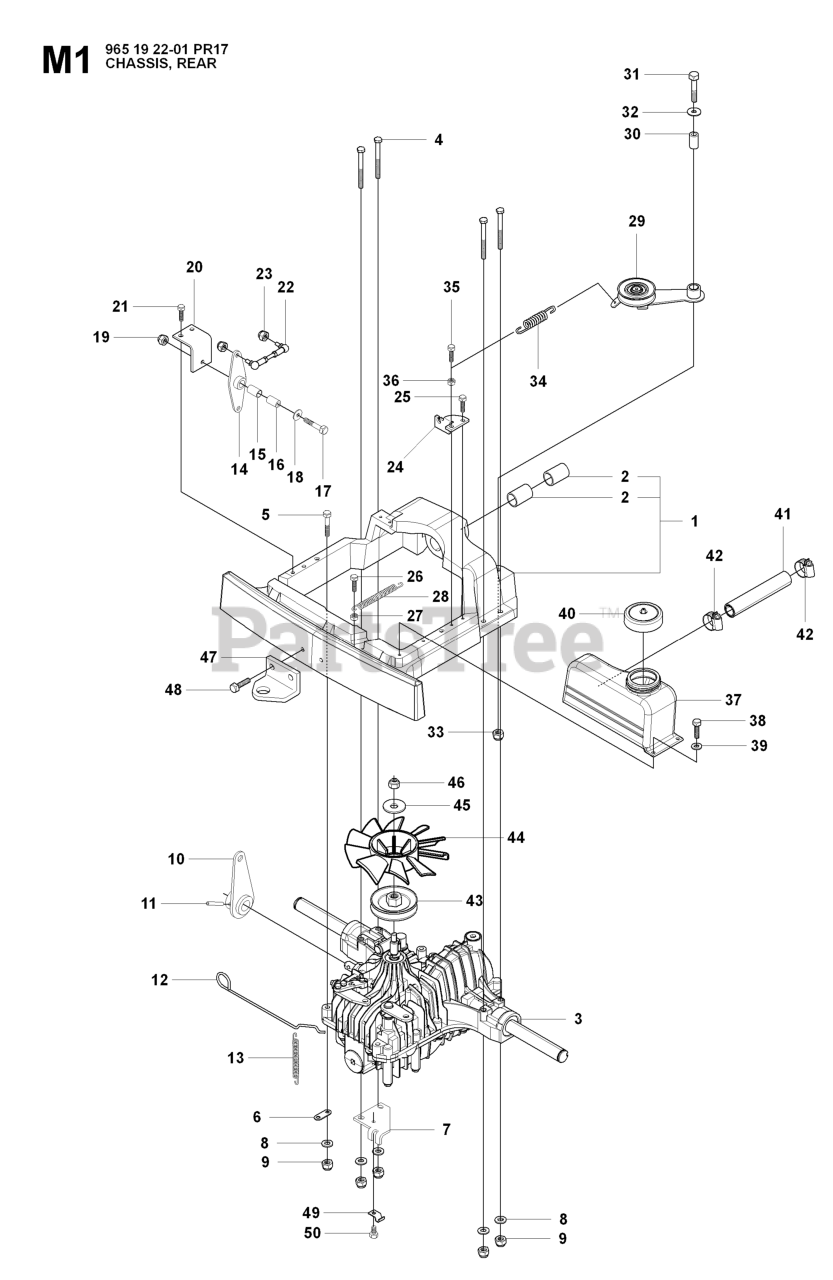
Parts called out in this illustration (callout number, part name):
8	WASHER BRB 8.4X17
9	LOCKNUT M8
14	ARM
17	SCREW
19	LOCKNUT M8
21	REPL BY 725 24 49-51
23	LOCKNUT M6
25	BOLT FLANGE - M6X20
33	LOCKNUT M8
38	BOLT FLANGE - M6X20
39	WASHER - 26X6.5X1.6
48	Screw M10x25
